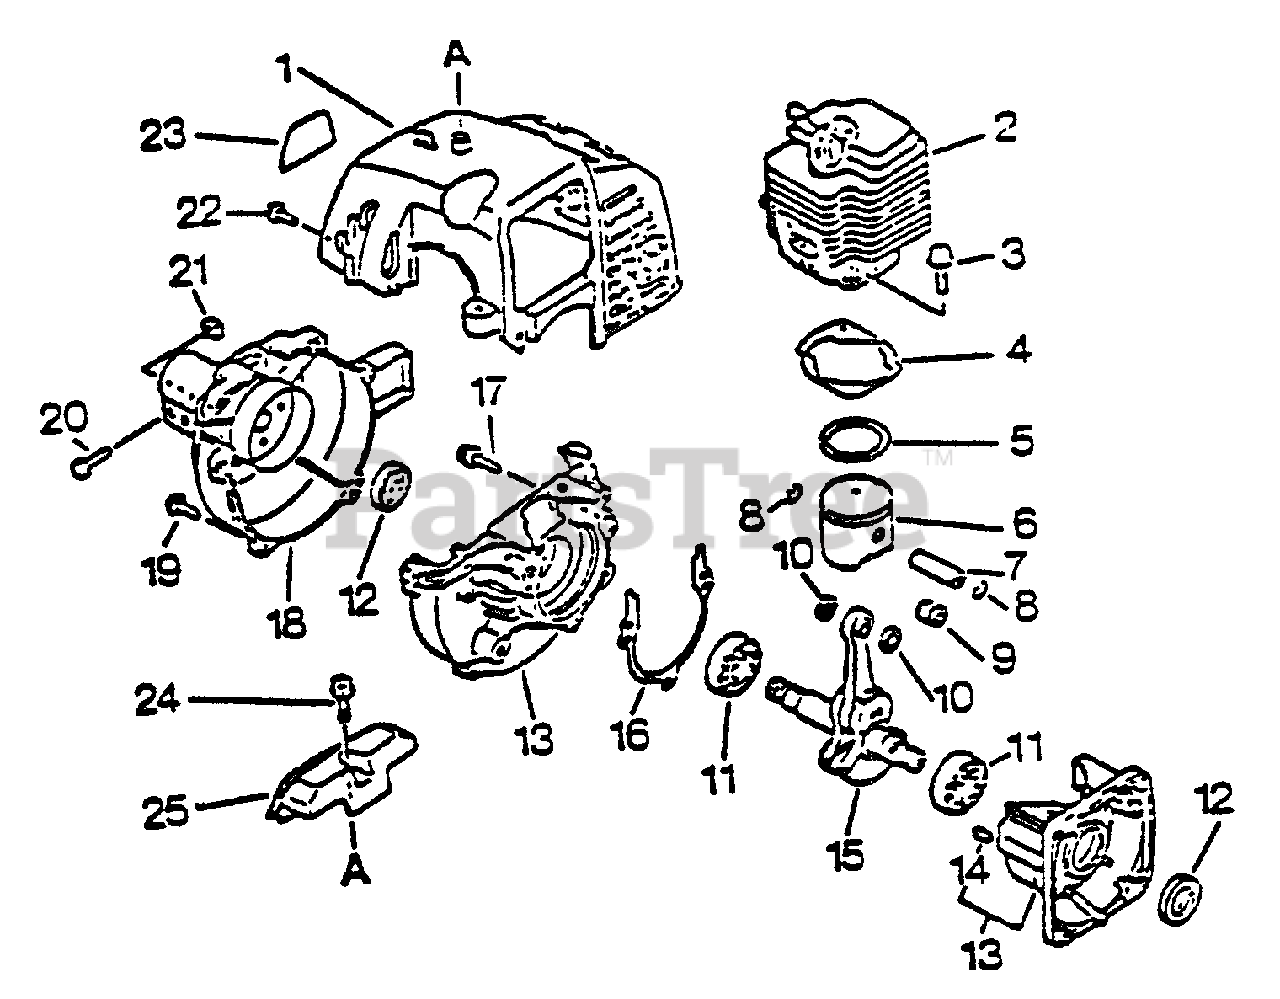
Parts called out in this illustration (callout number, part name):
1	COVER, ENGINE - GRAY
2	CYLINDER
3	BOLT 5×22
4	GASKET, CYLINDER
5	PISTON KIT
6	RING, PISTON
7	PIN, PISTON 8
8	RING, SNAP
9	BEARING, NEEDLE
10	WASHER, THRUST
11	BEARING, BALL - 6201 C3
12	SEAL, OIL 12
13	CRANKCASE KIT
14	PIN, LOCATING 4
15	CRANKSHAFT ASSY
16	GASKET, CRANKCASE
17	SCREW 5×28
18	FAN CASE ASSY
19	SCREW 4×18
20	BOLT 5×28
21	NUT M5
22	SCREW 4×12
23	LABEL - MODEL
24	SCREW 5×16
25	GUARD, TOP - BLACK
